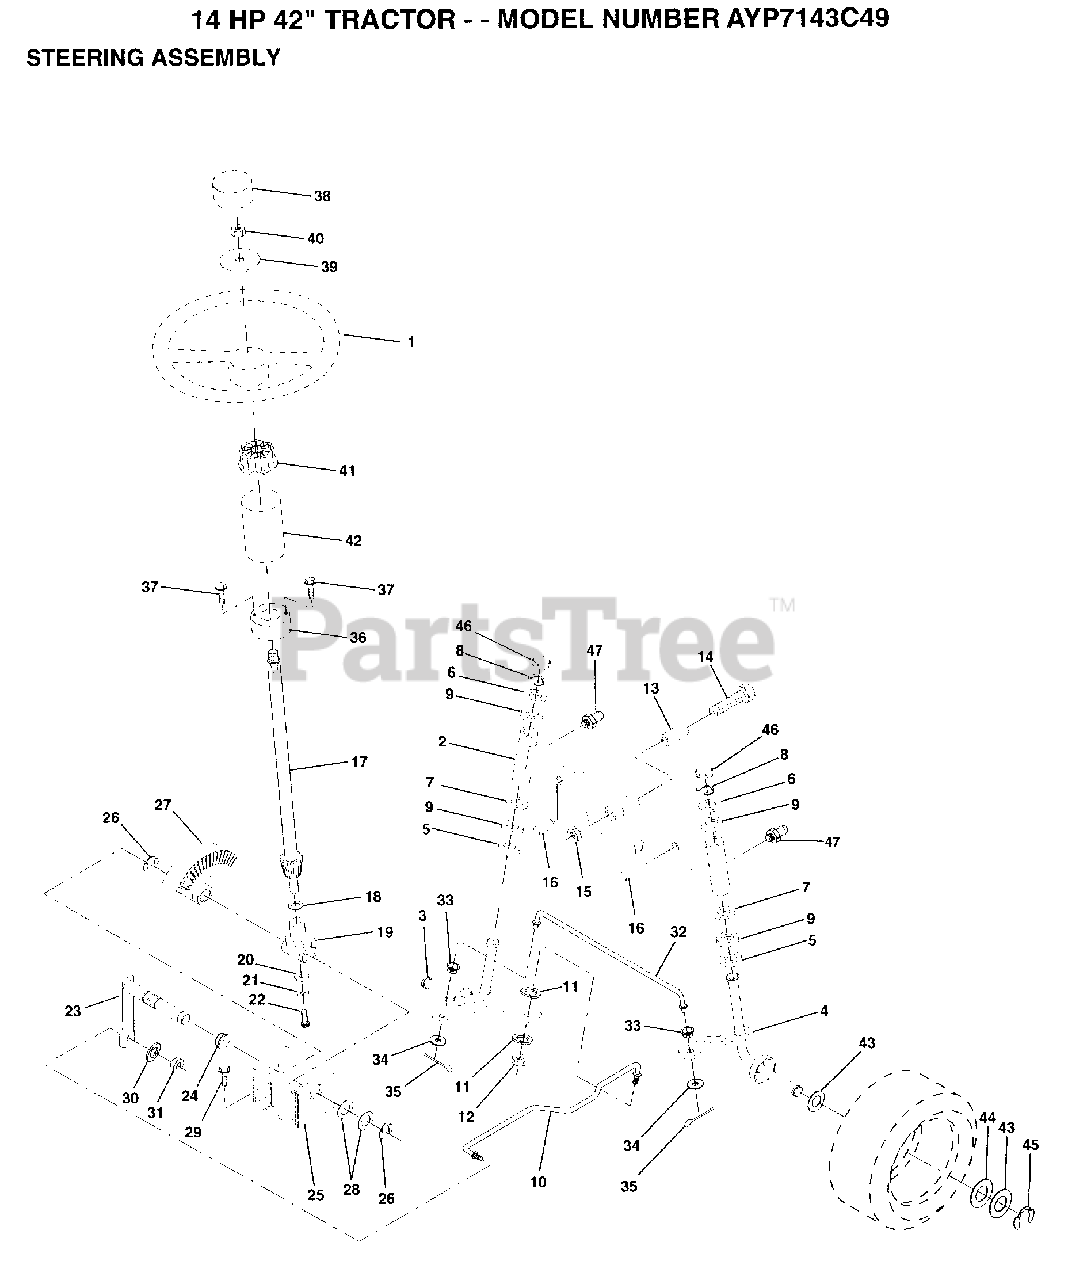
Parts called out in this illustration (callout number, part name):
2	AXLE ASM FRONT
3	SPINDLE LH
4	SPINDLE RH
5	WASHER .T
6	WASHER
7	WASHER
8	RING
9	COL. SRTG. BEAR.
11	LOCKWASHER
13	BEARING
14	BOLT HEX 5/8-11
15	"NUT-LOC,FLANGE LT"
16	AXLE PIN
17	SHAFT ASM
18	THRUST WASHER
19	SUPPORT.SHAFT
21	LOCKWASHER
22	"SCREW,SPECIAL"
24	NYLINER T
25	"BRKT,STEERING"
26	RING
27	GEAR SECTOR
28	WASHER .T
29	SCREW
30	LOCKWASHER
32	TIE ROD
33	BUSHING.DRAGLINK
34	WASHER
35	COTTER PIN
38	ST WHL INSERT CAP
39	WASHER T
40	GRIPCO NUT
41	ADAPTER-WHEEL LT
42	"TUBE, STR SHAFT"
43	WASHER
44	WASHER
45	RING
46	CAP
47	ZERK M
